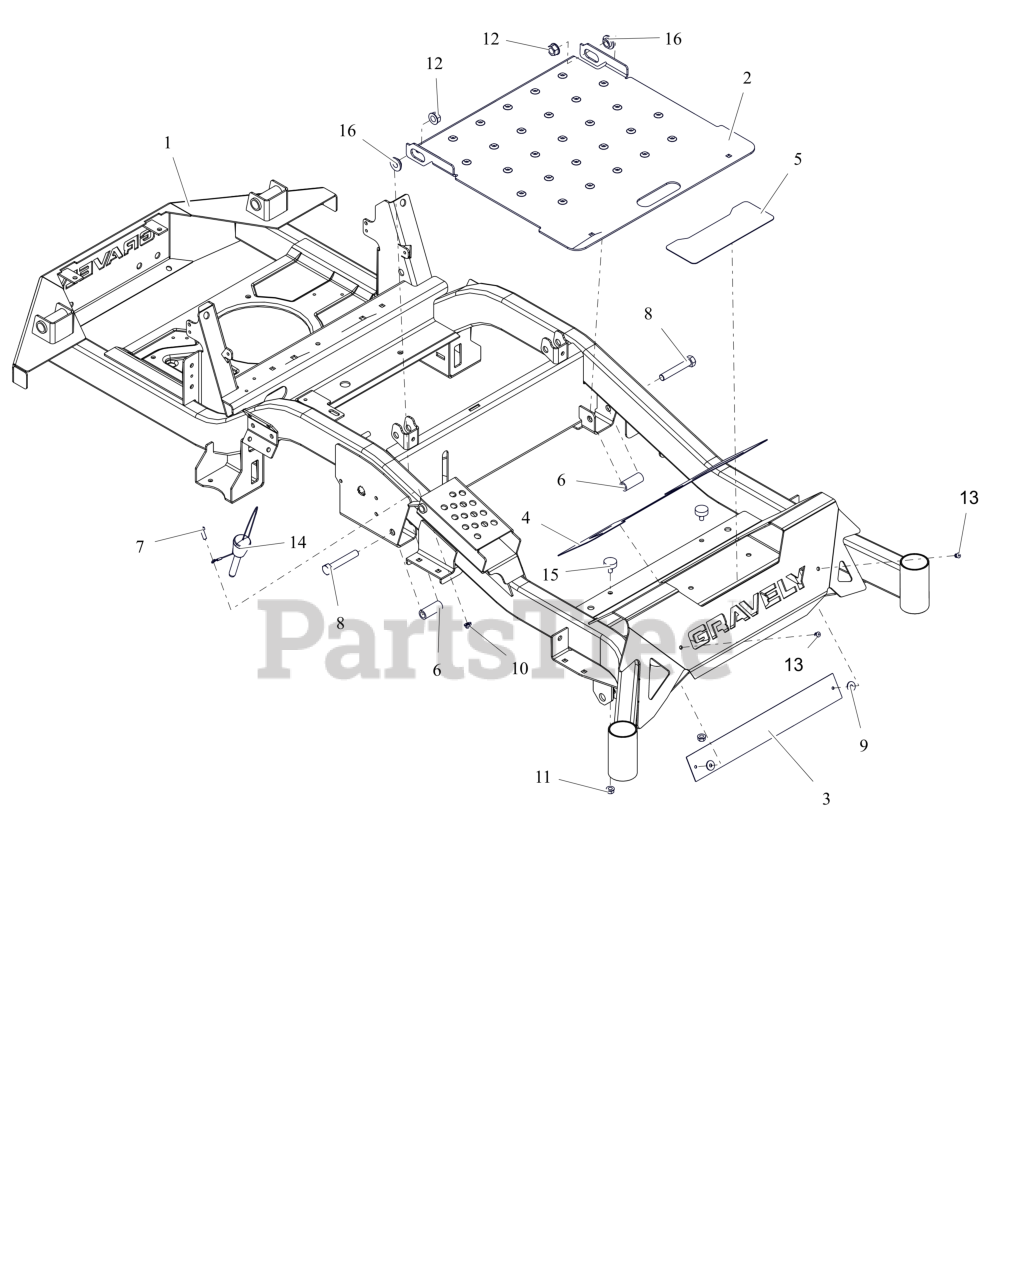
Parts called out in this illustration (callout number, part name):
1	WLDMT, MAIN FRAME -HD 44/52
2	KIT,ACCESS PANEL W/DECALS-RED
3	PLATE, BACK FOOT-REST XL
4	GRIP, FRONT
5	GRIP, STEP
6	SPACER, .515X.75X1.83
7	BLT, HEX .25-20X.75 G5 ZCC
8	BLT, HEX .50-13X3.00 G5 ZCC
9	WSHR, RBR W/ADHESIVE .25X.75X.06
10	NUT,NYL-FLG .25-20 GF ZCC
11	NUT,SPNLK-FLG .31-18 G5 ZCC
12	NUT-LK-TOP-FLG .500-13 GF ZCC
13	RIVET, .1875 AL/AL .126-.250
14	PIN, MAGNETIC .50X2.50
15	BUMPER, RUBBER
16	BSHG-FLG .515X.750X.310X1.120
